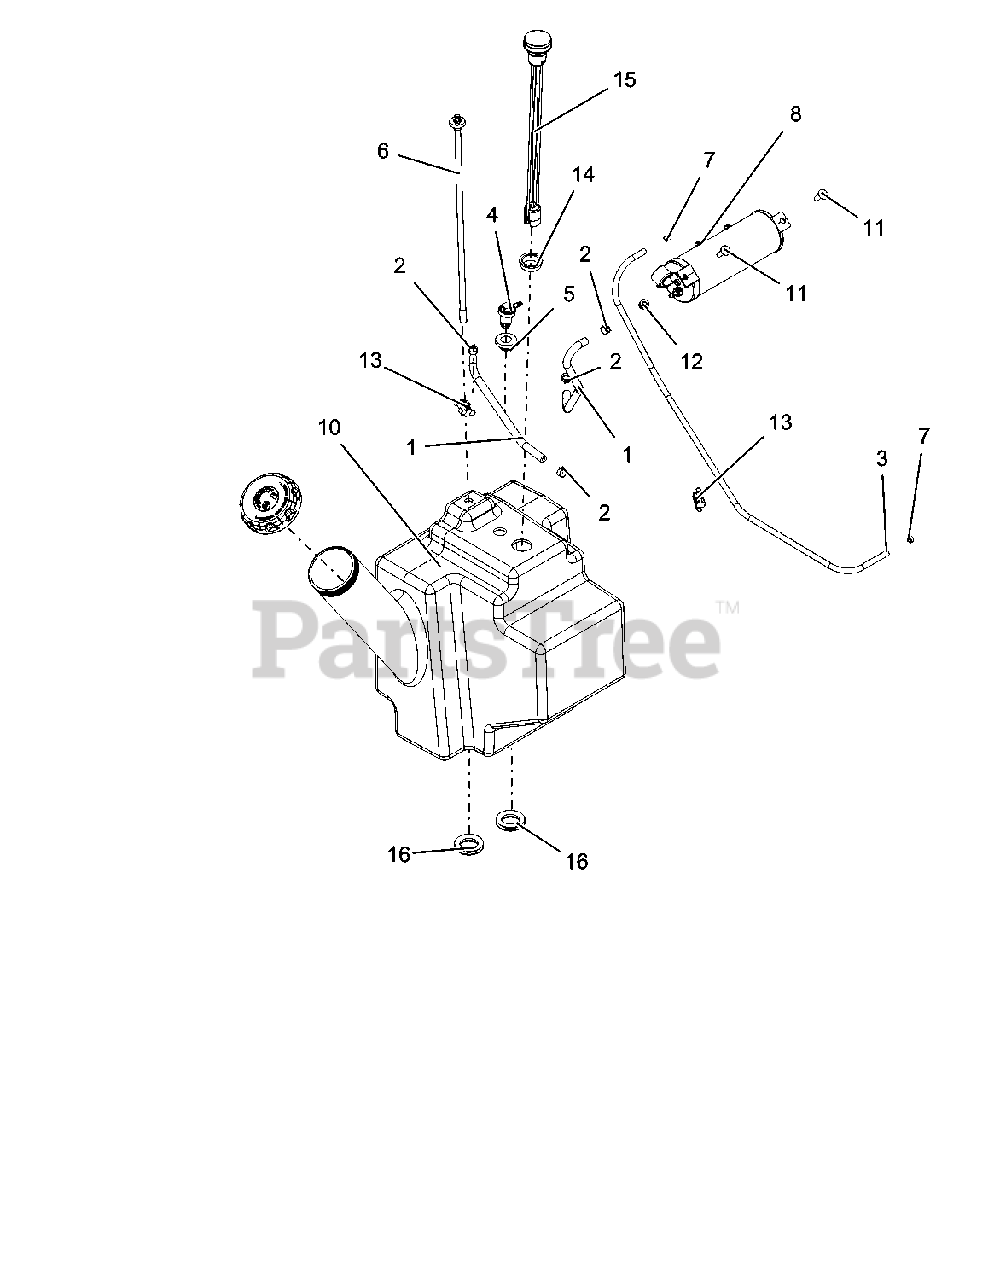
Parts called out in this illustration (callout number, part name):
1	HOSE, .25 LOW-PERM BULK GAS
2	CLAMP, FUEL LINE
3	HOSE, .188 LOW-PERM BULK GAS
4	VALVE, COMBINATION
5	GROMMET, REMOTE VENT NITRILE
6	ASS'Y, PROSTANCE FUEL PICK-UP
7	CLAMP-HOSE, SPRING .188
8	CANISTER, CARBON 9.3G CAP.
10	ASM, FUEL TANK
11	BLT-RDHDSQNK .31-18X1.00 G5YZ
12	NUT-LK-NYL-FLG .31-18 YWZC
13	CLIP, T, .38-.50
14	GROMMET, FUEL GAUGE
15	GAUGE, REMOTE FUEL SEALED 15"
16	GROMMET 1.25ID X 1.5OD
